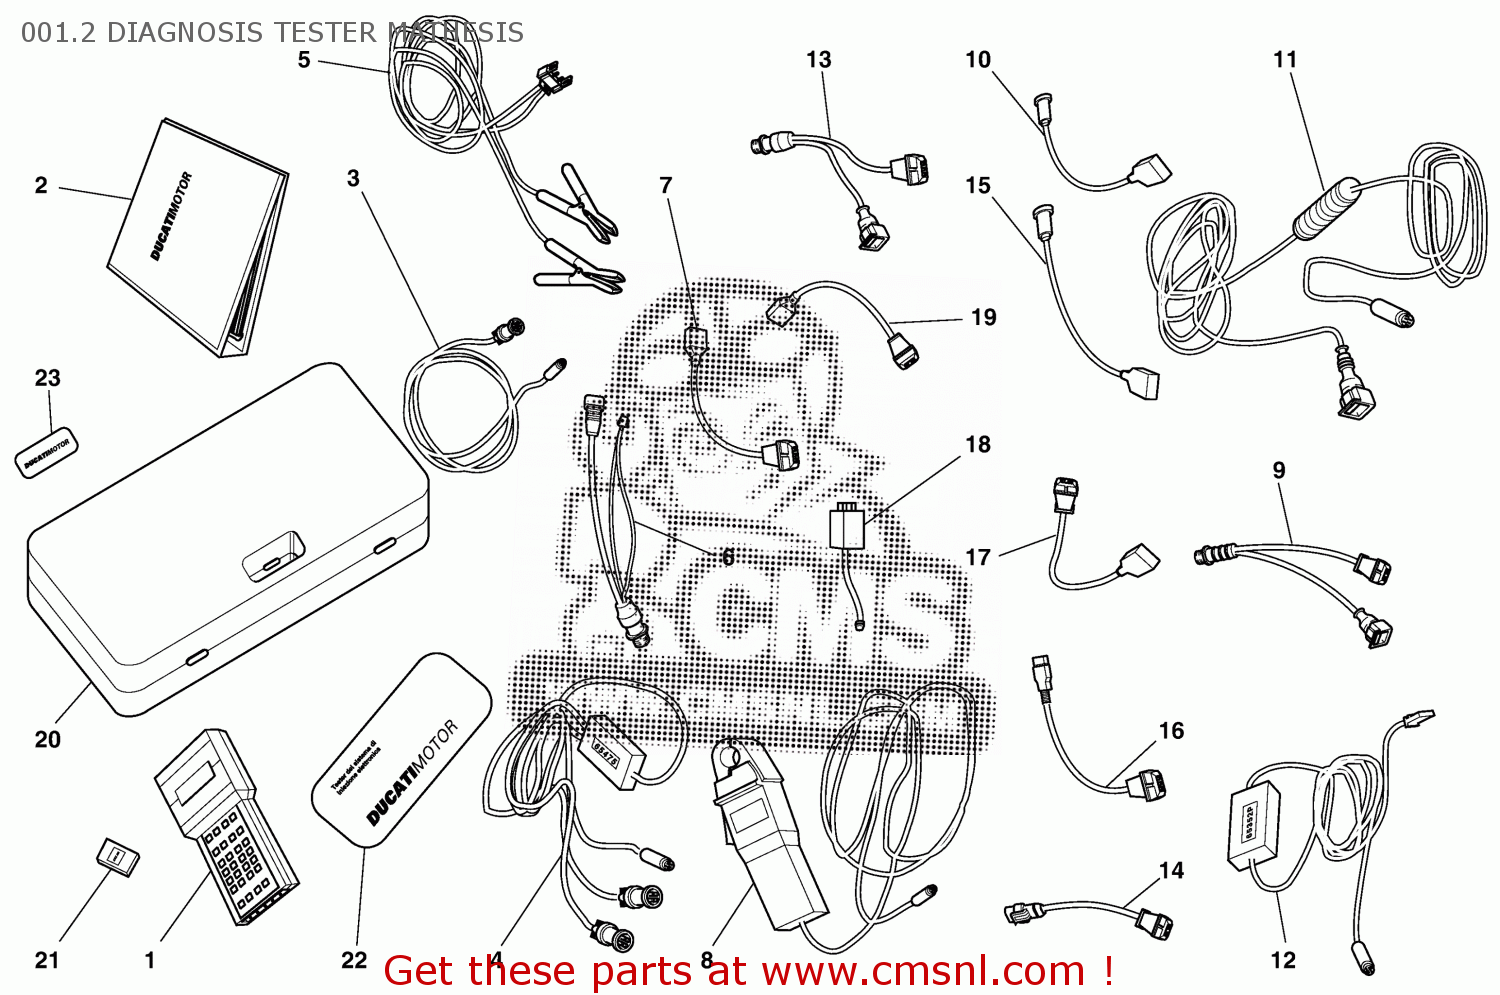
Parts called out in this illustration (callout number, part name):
1	BARE MATHESIS
2	INSTRUCTIONS HANDBOOK GERMAN
3	MAIN CABLE MATHESIS
4	PICK-UP CONTROL CABLE
5	BATTERY MAINS CABLE
6	MAINS CABLE ADAPTER FOR SELF DIAGNOSIS
7	PRESSURE DETECTOR
8	AMPEROMETER PLIER
9	ADAPTER FOR 3 WIRES PICK-UP TEST CABLE
10	SENSOR, AIR TEMPERATURE
11	CABLE FOR POTENTIOMETER ADJUSTEMENT
12	TEST CABLE AND SPEED INDICATOR ADJUSTEME
13	ADAPTER FOR 2 WIRES PICKUP TEST CABLE
14	ADAPTER FOR POTENTIOMETER ADJUSTEMENT
15	SENSOR FOR SMALL THROTTLE POTENTIOMETER
16	SENSOR FOR THROTTLE POTENTIOMER SAMPLING
17	SENSOR FOR AIR/WATER TEMPERATURE SAMPLIN
18	SAFETY REMOTE SWITCH
19	SAMPLING PICKUP SENSOR, 2 WIRES
20	CASE WITH SPONGE
21	MEMORY CARD GERMAN
22	EMBLEM DUCATI
23	EMBLEM DUCATI
